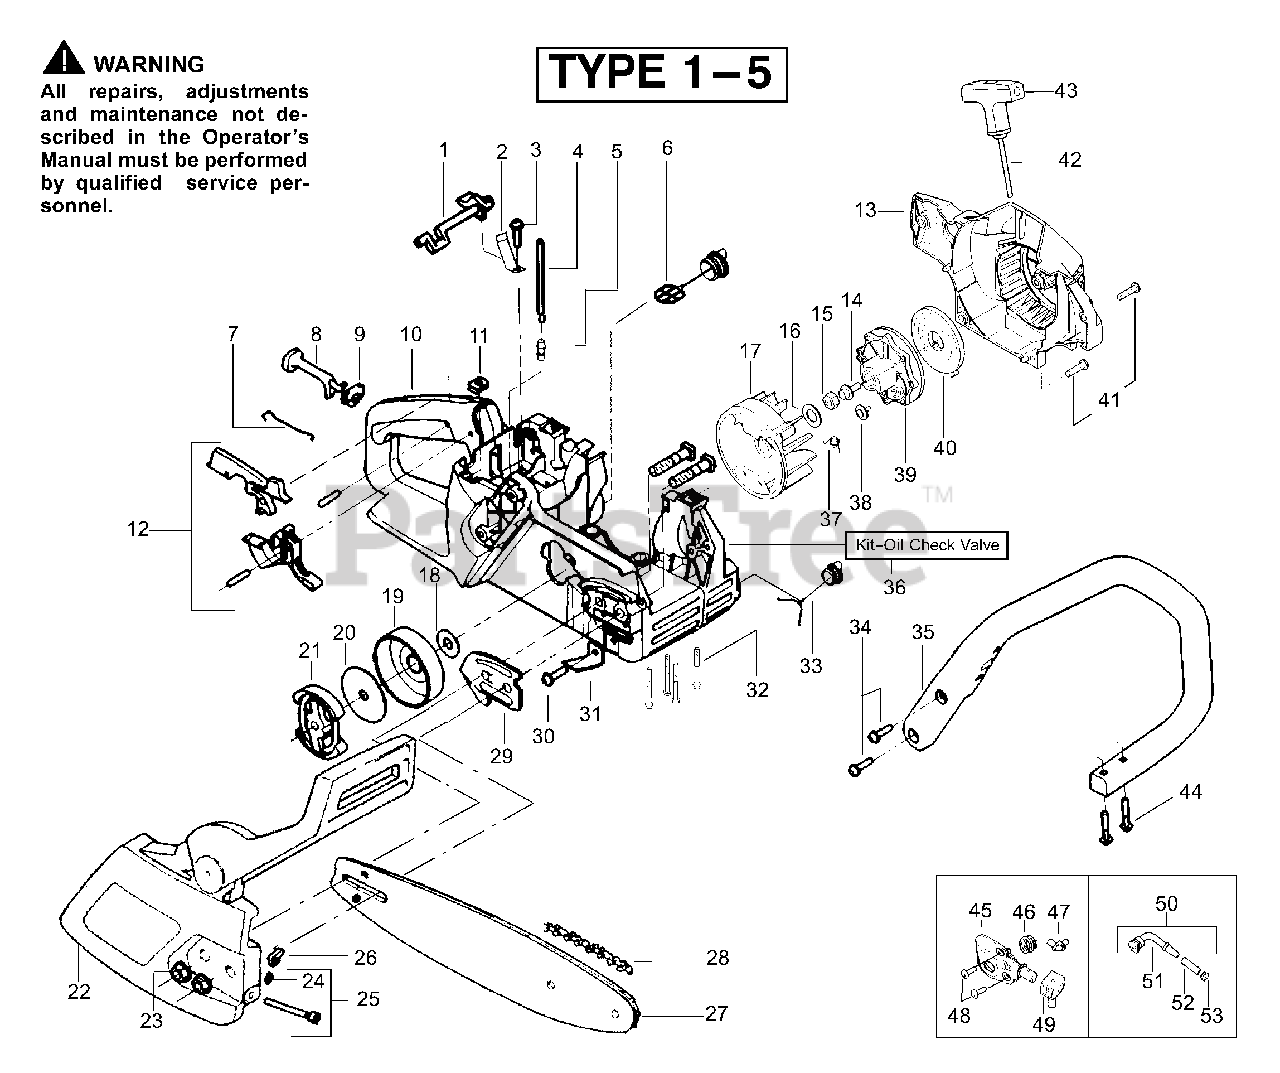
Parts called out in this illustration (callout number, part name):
1	Lever-Switch
2	Spring-Switch
4	Kit-Fuel Line (Large)
6	Assy-Fuel Cap
7	Wire-Throttle
8	Lever-Choke
9	Grommet-Choke Knob
10	Assy-Chassis
11	Nut-Speed
12	Kit-Trigger & Lockout
13	Housing-Fan
15	Nut-Flywheel
16	Washer-Flywheel
17	Assy-Flywheel
18	Washer - Thrust
19	Assy-Drum W/brg.
20	Washer-Clutch
21	Assy. - Clutch
22	Assy-Chain Brake
23	Nut-Bar Mounting
24	Retainer-Bar Adjust
25	Kit-Bar Adjust
26	Pin-Bar Adjust
28	Chain 18"
29	Plate-Bar Mounting
31	Chain Catcher
33	Assy-Oil Cap
35	Handle-Front
36	Kit-Oil Check Valve
37	Spring - Starter Dog
39	Pulley-Starter
40	Spring-Starter
42	Kit-Rope
43	Handle-Starter
45	Kit-Oil Pump
46	Gear-Worm Spring
47	Elbow-Oil Pickup
49	Seal Block
50	Assy-Oil-Pickup
51	Pickup-Oiler
52	Filter-Oil
53	Plug-Oil Filter
